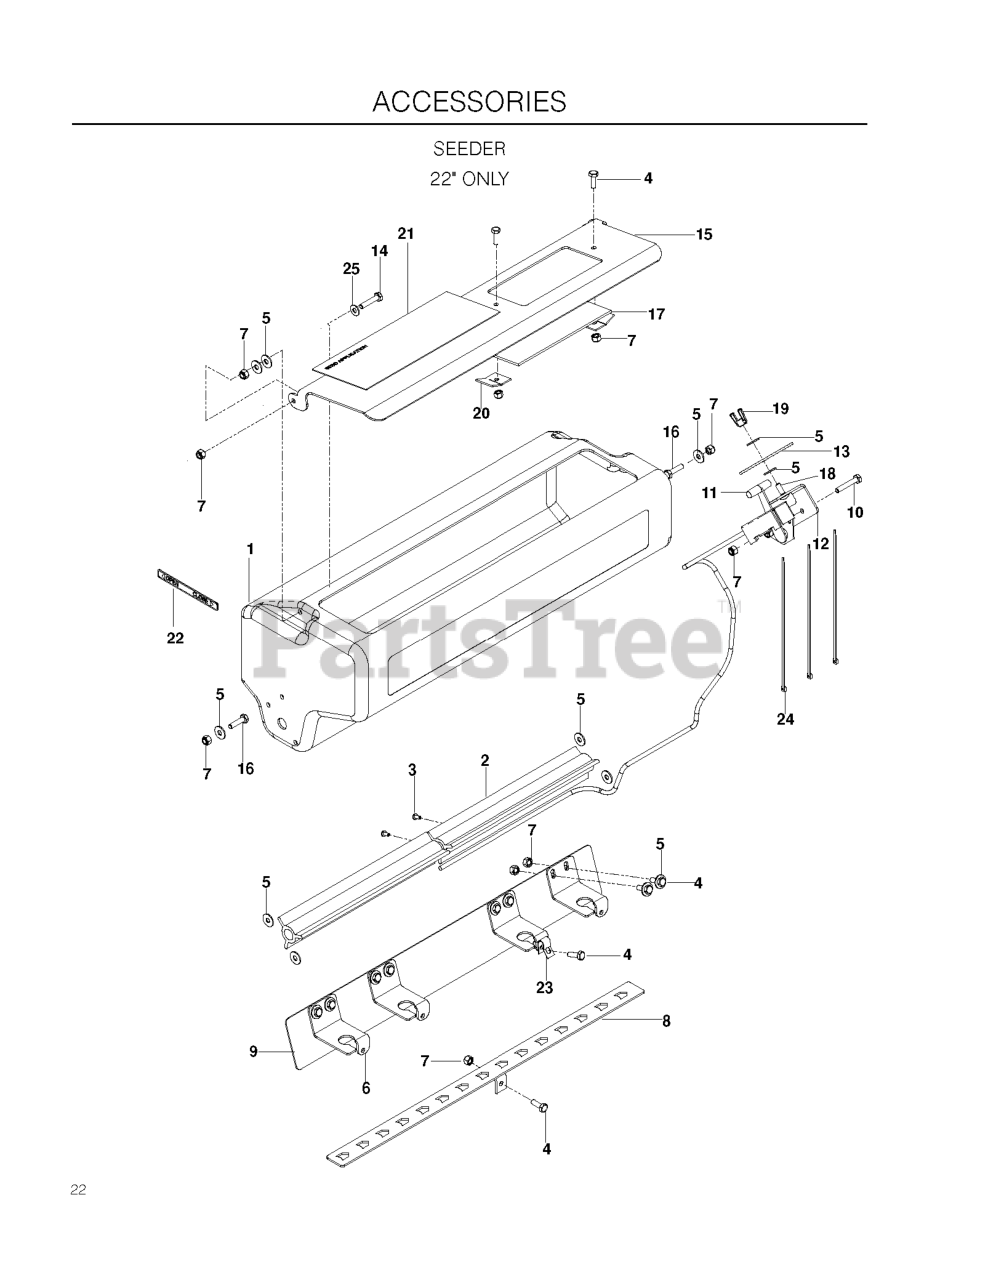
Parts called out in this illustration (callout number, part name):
1	SEED BOX CHARCOAL GREY
3	R/B 108495 SCR SLF TP 8-32X3/8
4	HCS 1/4C X 3/4 HCS
5	WASHER 1/4 FLAT
7	NUT.1/4-20.HEX.NYLOC.ZD
10	SCW 1/4-20 X 1-1/2 HEX
11	CONTROL, PUSH/PULL ASSEMBLY
14	BOLT HEX 1/4 X 1-1/4
15	SEED DOOR ORANGE
16	HCS 1/4 X 1
17	SEED WINDOW
18	RHSNB 1/4C X 3/4
19	WING NUT 1/4
20	WINDOW CLIP
21	DECAL, SEED APPL
22	DECAL, OPEN/CLOSE
23	BRACKET, PUSH/PULL
24	TIE, PLASTIC
25	WASHER 1/4 SAE
